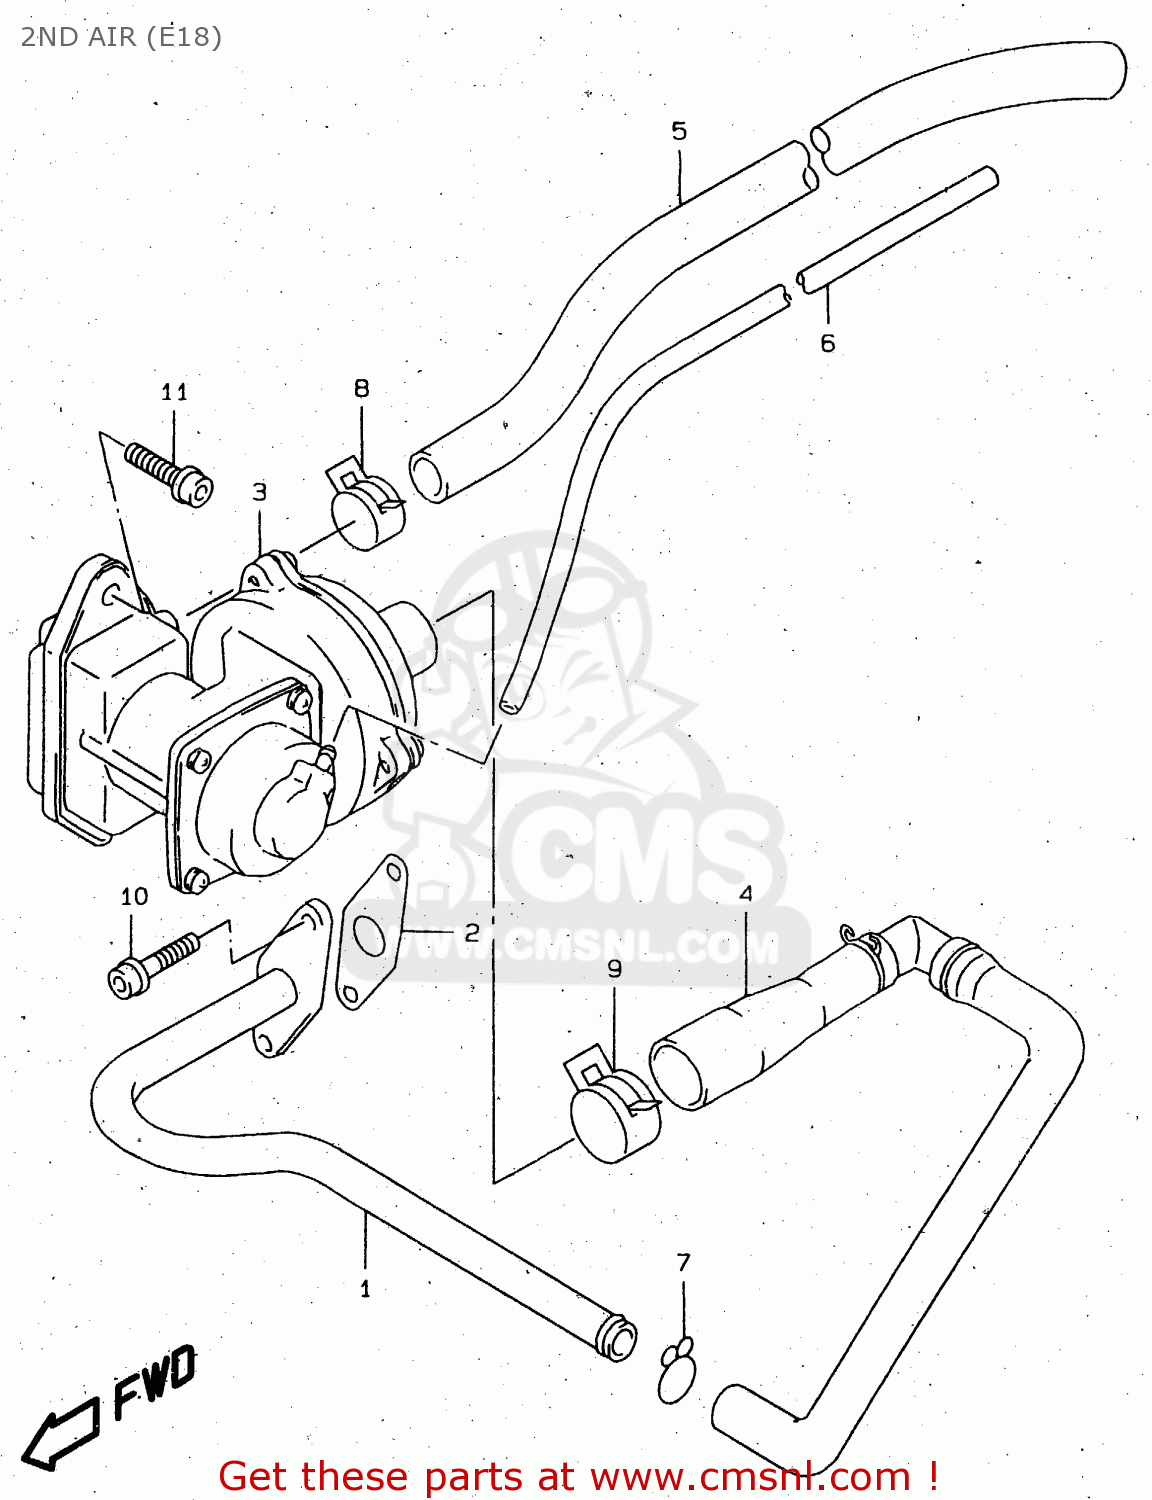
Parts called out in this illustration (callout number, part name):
1	PIPE, 2ND AIR
2	GASKET,SECOND AIR PIPE (N (NAS)
3	VALVE ASSY,2ND AIR REED
4	HOSE ASSY,2ND AIR
5	HOSE(12X16X600)
6	HOSE(4X7X600)
7	CLIP
8	CLIP
9	CLIP
10	BOLT MAGNETO S
11	BOLT
